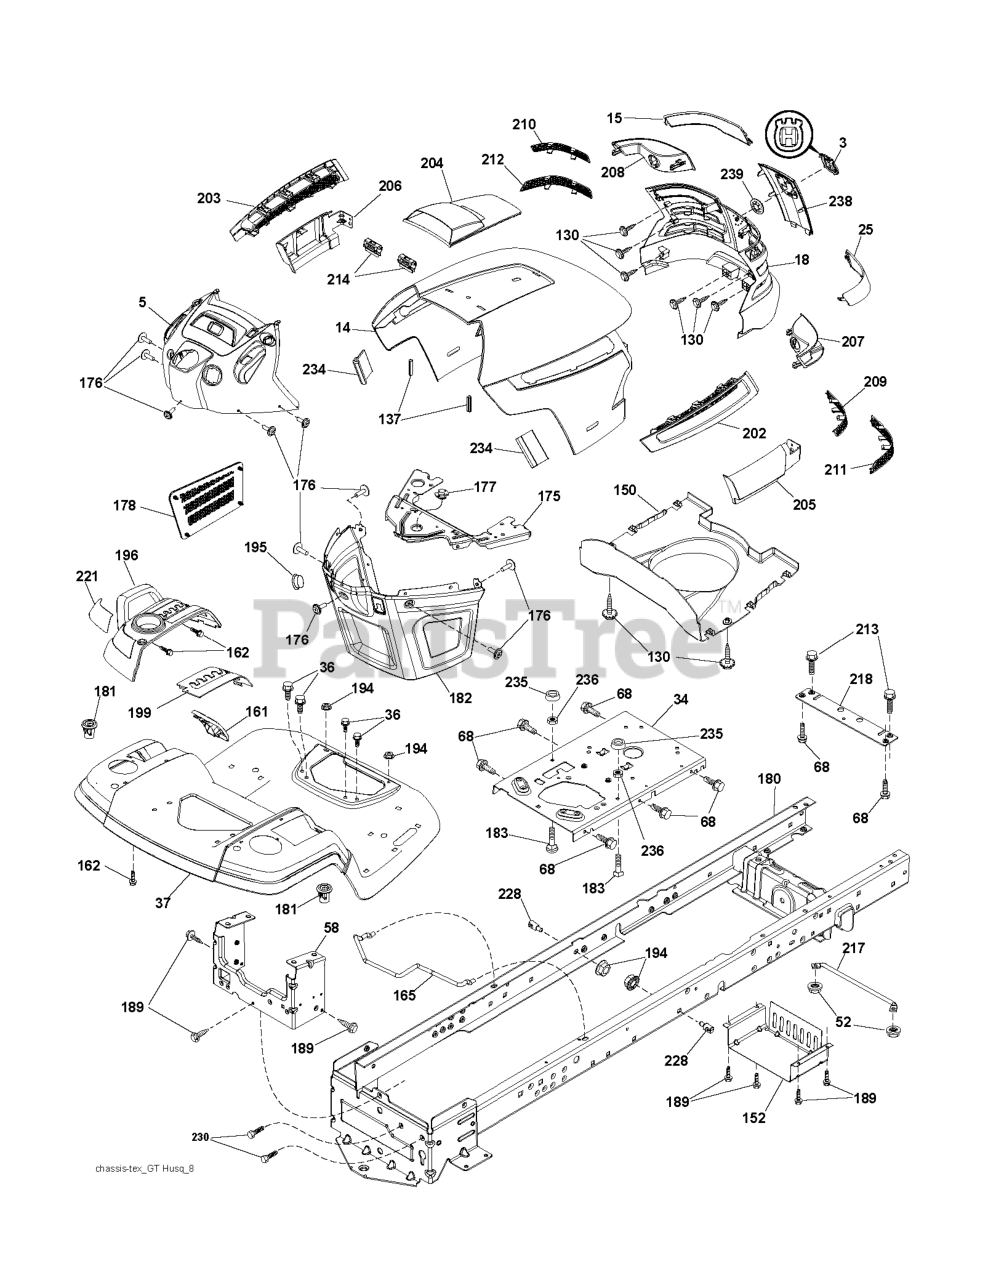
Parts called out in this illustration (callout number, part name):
3	RP LOGO
5	DASH.ASM.HUSQ.GT.E.RECT.W/CK
14	HOOD
15	LENS.LH.TEX.GT.HUSQ.CL
18	GRILL.ASM.HUSQ.TG/CRD.W/TRIM
25	LENS.RH.TEX.GT.HUSQ.CL
34	PLATE.ENGINE.WELDED.CHASSIS
36	SCREW 5/16"
37	FENDER.PNT.TX.GT.CH/FW.ORANGE
52	LOCKNUT
58	DRAWBAR.UPPER.2PC,LRG.FENDER
68	Screw 5/16-18 x 1/2 Hex, Self Tapping 5/16-18 x 1/2
130	SCREW
137	BUMPER DASH
150	AIR.DUCT.HOOD.TEX.GT.HUSQ
152	SHIELD.BROWNING.W/TEX
161	CONSOLE.FUEL.WINDOW.HU
162	SCREW.HI-LO.CONSOLE
165	SUPPORT.TANK.REAR.W/TEX
175	PLATE.CROSSMEMBER.HUSQ
176	SCREW.#10-24X5/8.RN.QU
177	BUSHING, STEERING
178	CARGO.ASM.NET.TXGT.W/C
180	CHASS.WLDMNT.TL.12GA/2P.48/54
181	BUSHING.MNT.FEND.CRGO.
182	DASH.LOWER.COMMON.12V.ADAPTOR
183	BOLT.5/16-18X1-1/4 FULL.THREAD
189	SCREW
194	NUT LOCK HEX FLANGE 5/16-18
195	PLUG.HOLE.DASH.LOWER.12V.BLK
196	RP CONSOLE.ASM.DECKLFT.W/
199	PLATE.DECK.LIFT.HUSQVARNA.GT
202	VENT.SIDE.HOOD.HUSQ.RH.GREY
203	VENT.SIDE.HOOD.HUSQ.LH.GRAY
204	HOOD VENT
205	SKIRT.HOOD.SIDE.HUSQ.RH.GREY
206	SKIRT.HOOD.SIDE.HUSQ.LH.GREY
207	BEZEL.RH.TEX.GT.HUSQ
208	BEZEL.LH.TEX.GT.HUSQ
209	INSERT.HEX.GRILL.HUSQ.GREY
210	INSERT.HEX.GRILL.HUSQ.
211	INSERT.HEX.GRILL.HUSQ.
212	INSERT.HEX.GRILL.HUSQ.
213	BOLT
214	CLIP.RETAINER.TINNER.
217	ROD.PIVOT.HOOD
218	X-PIECE.HOOD.STOP.NON/
221	REFLECTOR.LH.TEX GT HU
228	STUD.FASTNER.W/ANTI-ROTATE
230	BOLT.SHOULDER
234	BUMPER.HOOD.TEX.HUSQVARNA
235	SPACER FENDER
236	NUT.CENTERLOCK.5/16-
238	TRIM.HUSQ.TG/CRD.SERVICE
239	NUT PUSH M
